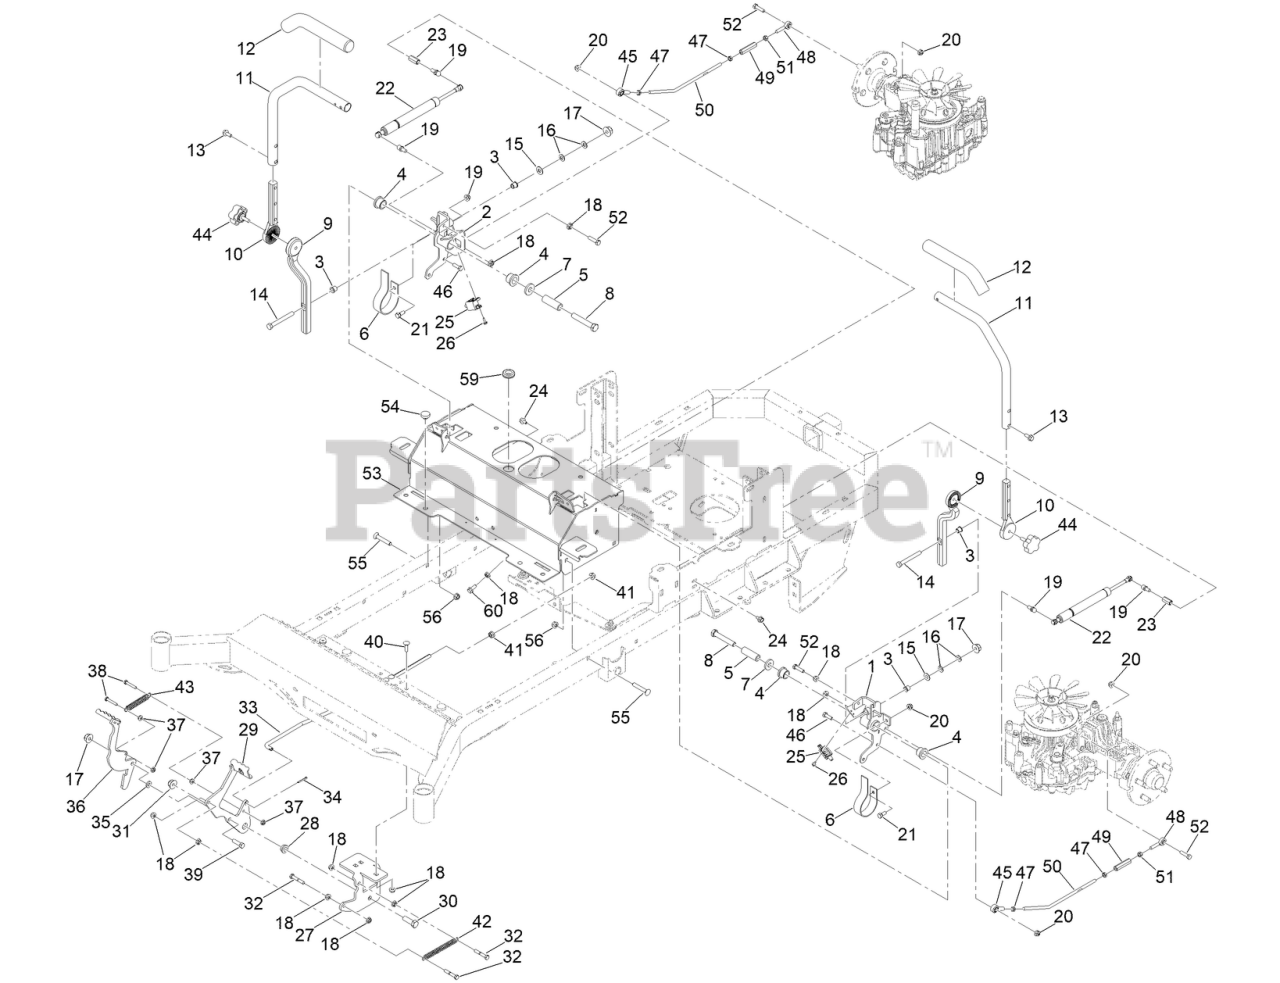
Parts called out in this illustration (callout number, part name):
1	LH PIVOT ASM
2	RH PIVOT ASM
3	BUSHING-FLANGE
4	BUSHING-FLANGE
5	SLEEVE-PIVOT
6	SPRING-LEAF
7	1/2 FENDER WASHER 1-1/4IN OD ZINC
8	1/2-13 X 3 HEX C/S GR 5 ZINC W/LOCTITE
9	ADJUSTABLE LWR DRIVE ARM
10	ADJUSTABLE UPP DRIVE ARM
11	MOWER DRIVE HANDLE TUBE ABC
12	CONTROL ARM HANDLE GRIP
13	SCREW-HHF
14	SCREW-HH
15	WASHER-FLAT
16	WASHER-BELLEVILLE
17	3/8-16 NYLON INSERT FLANGE L/NUT YZ
19	5/16-18X1.286 DAMPER BALL STUD (.562 TL)
20	NUT-HF, NI
21	SCREW-HH
22	CONTROL ARM DAMPER
23	STANDOFF-HEX
24	SCREW-HHF
25	NO PLUNGER LIMIT SWITCH
26	8-32 X 1/2 IND. HWH SLOT TYPE F TCS ZINC
27	MWR FRAME BRAKE MTG BRKT PAINT
28	1/2IN ID X 3/4IN OD X 3/8IN FLANGE BUSH
29	MWR BRAKE LOCK LEVER ASSY PAINTED
30	SCREW-HH
31	NUT-LOCK
33	TTQ 1310 BRAKE ROD
34	PIN-COTTER
35	3/8 ID X 3/4 OD X .125 THK BRONZE WASHER
36	MWR BRAKE UNLOCK LEVER ASSY PAINTED
37	1/4-20 HEX FLANGE NUT
38	1/4-20 X 1-1/4 HEX C/S GR 2 ZINC
39	SCREW-HH
40	BOLT-CARR
41	3/8-16 HEX FLANGE NUT W/SERR ZINC YELLOW
42	2020 MWR BRAKE PEDAL TENSION SPRING
43	MWR BRAKE PEDAL RELEASE SPRING
44	5/16-18 X 1 SL 5-LOBE MALE ST KNOB 1.90
45	5/16-24 SPHER ROD END ZINC LH THD FEM
46	SCREW-HH
47	NUT-JAM
48	ROD END-BALL JOINT
49	NUT-SLEEVE
50	ROD-DRIVE ARM
52	SCREW-HH
53	ASM, GT-TRAC [GRAY]
54	PUSH-IN RUBBER BUMPER MWR FLOOR
55	SCREW-CARR
59	GROMMET-RUBBER
60	5/16-18 X 3/4 HEX FLANGE BOLT GR 8 YZ
